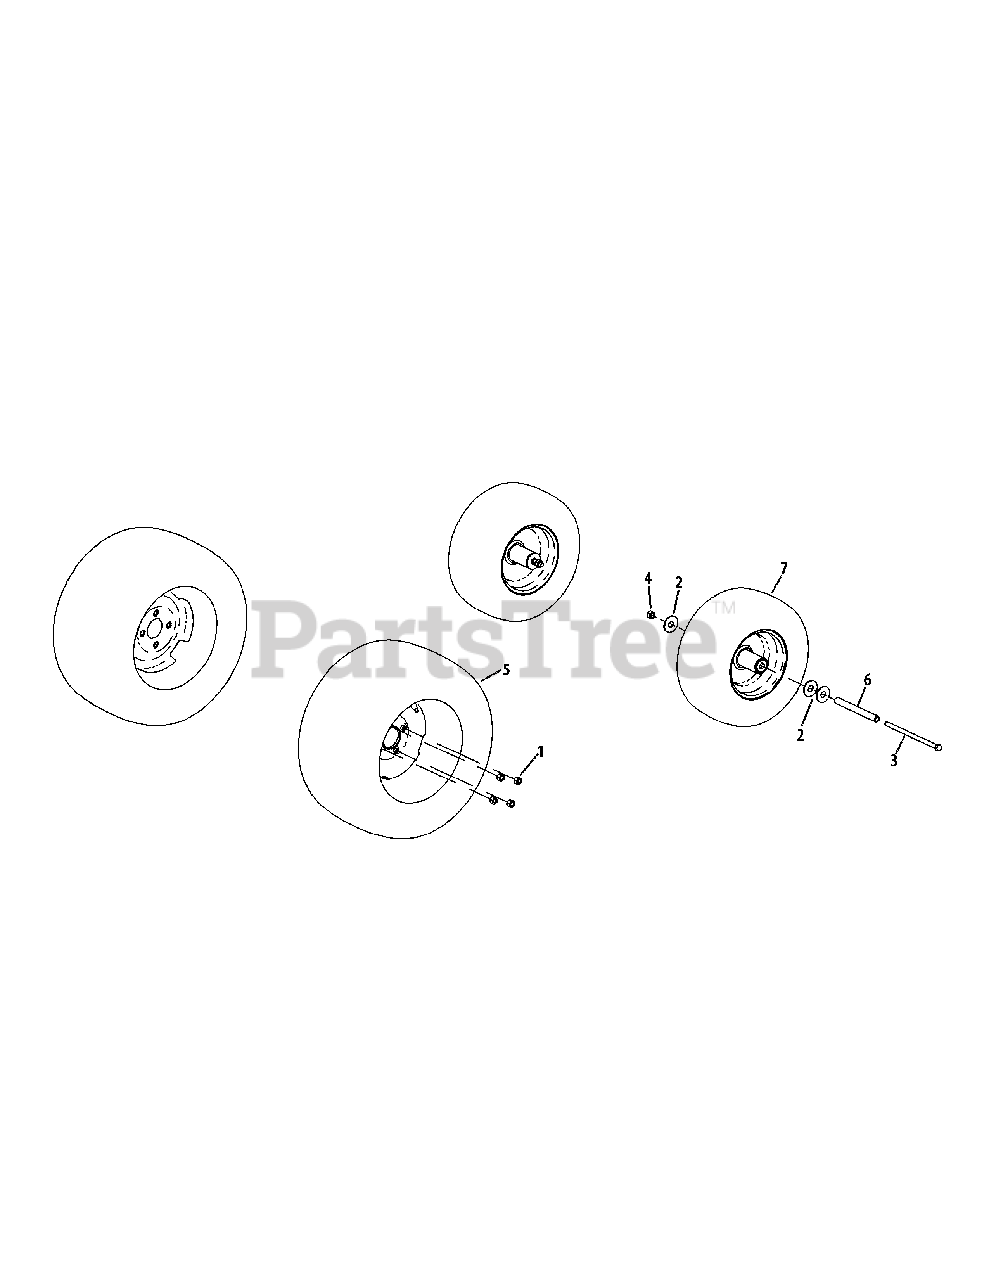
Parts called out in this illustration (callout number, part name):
1	Lug Nut, 1/2-20
2	Washer, .781 x 2.00 x .105
3	Hex Screw, 1/2-20 x 9.50
4	Nut, 1/2-20, Lock
5	Wheel Assembly, 24 x 12.00-12
6	Spacer, .51 x .75 x 7.49
7	Front Wheel Assembly, 16 x 6.50-8
7	Front Caster Tire Only 16 X 6.5-8
